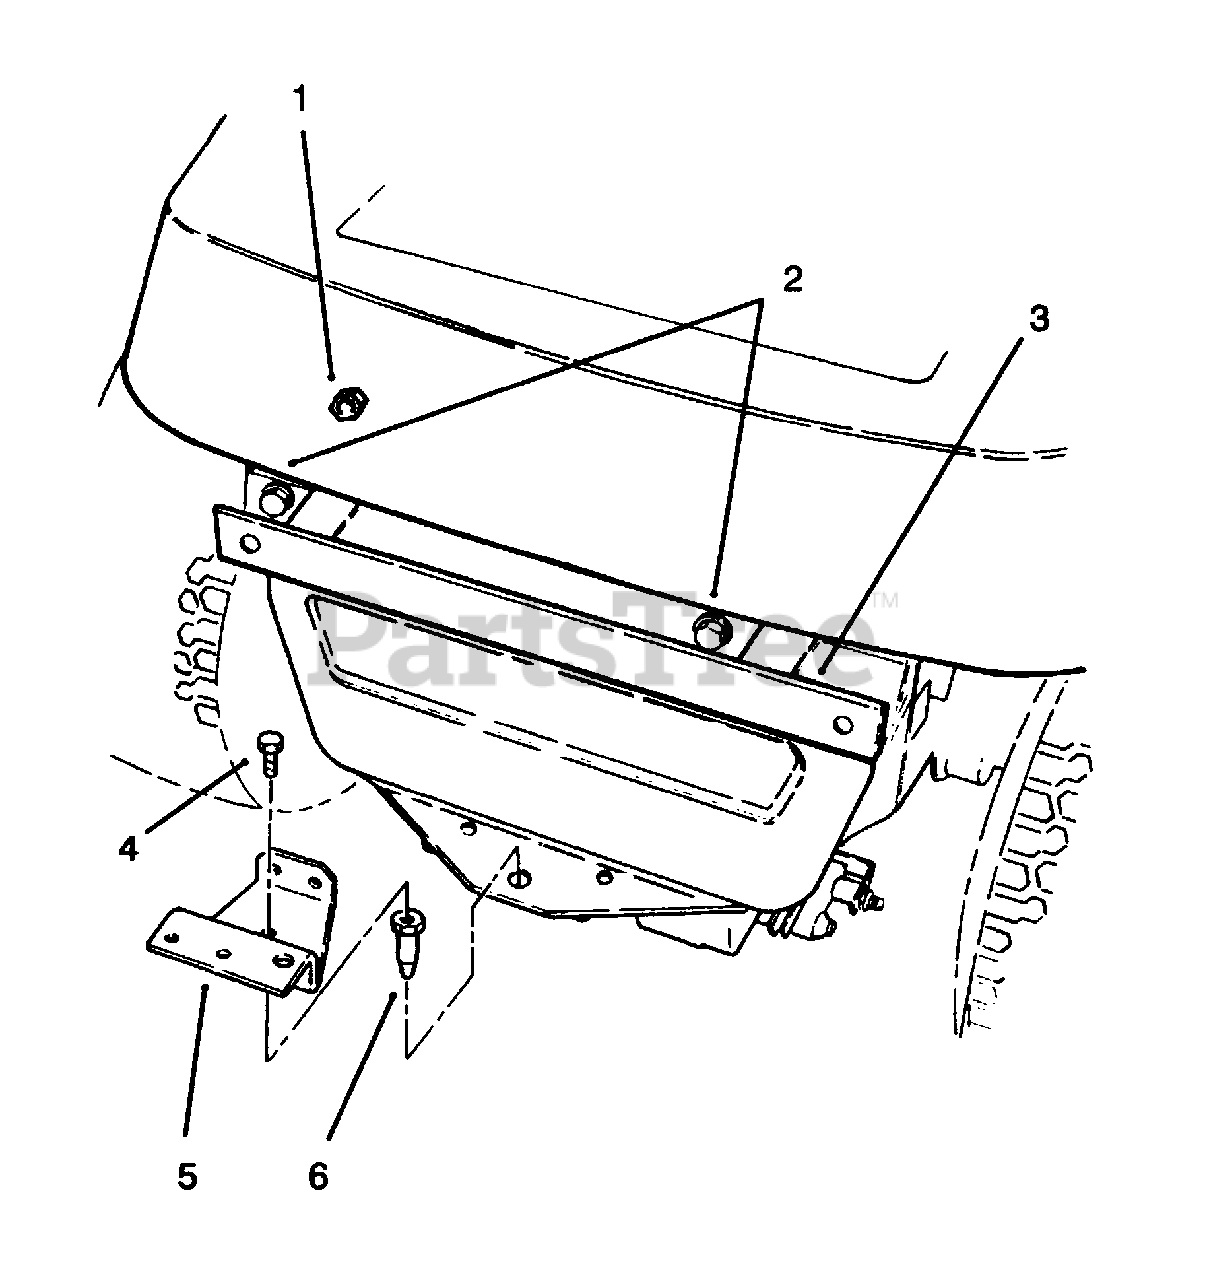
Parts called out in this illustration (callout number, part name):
2	Capscrew
3	Bracket-Channel
4	Capscrew
5	Bracket-Bagger Mounting
6	Pin-Mounting, Lower
